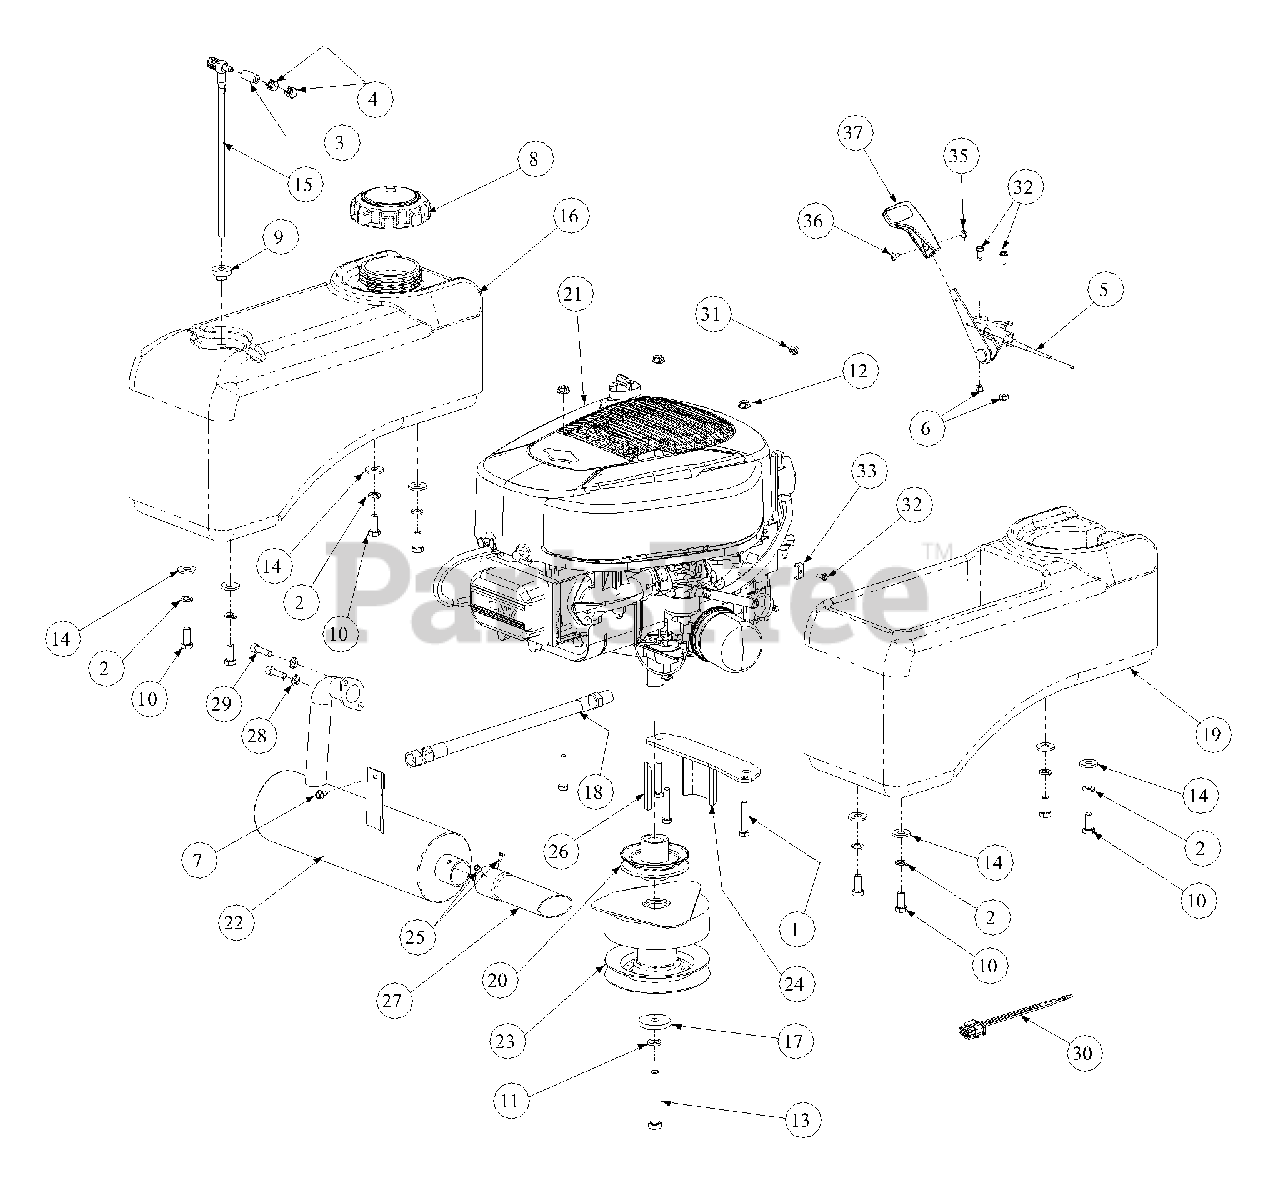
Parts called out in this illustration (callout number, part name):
1	Hex Head Cap Screw, 5/16-18 x 1-3/4
2	Lock Washer, 3/8 Zinc
3	Hose, 1/4" Fuel Line
4	Clamp, Union
5	Throttle Control Cable
6	Lock Nut, Nylon Insert, 10-32
7	Self Tapping Screw, 1/4-20 x 1/2
8	Fuel Cap
9	Fuel Tank Groment
10	Hex Cap Screw, 3/8-16 x .88
11	Lock Washer, 7/16
12	Lock Nut, Hex Flange, 5/16-18
13	Hex Cap Screw, 7/16-20 x 4.0
14	Flat Washer, .406 ID x 1.0 OD x .105
15	Fuel Pickup Fitting
16	Fuel Tank
17	Flat Washer, 7/16 ID x 1.75 OD x .250
18	Oil Drain Extension Hose
19	Utility Bin
20	Electric PTO Engine Pulley
21	18.5HP Briggs Engine
22	Briggs Muffler
23	Ogura JD08 Electric Clutch
24	Clutch Retainer Assembly
25	Screw, 8-32 x .375, Hex Washer
26	Key, 1/4 x 1/4 x 2.75
27	Exhaust Pipe
28	Lock Washer, 5/16
29	Socket Head Cap Screw, 5/16-18 x 1.00
30	Harness Adaptor
31	Starter Side Lock Nut 1/4-20
32	Screw, #10-32 x 0.500
33	Throttle Cable Clamp
35	Nut, 8-32
36	Machine Screw, 8-32 x .375
37	Throttle Control knob
